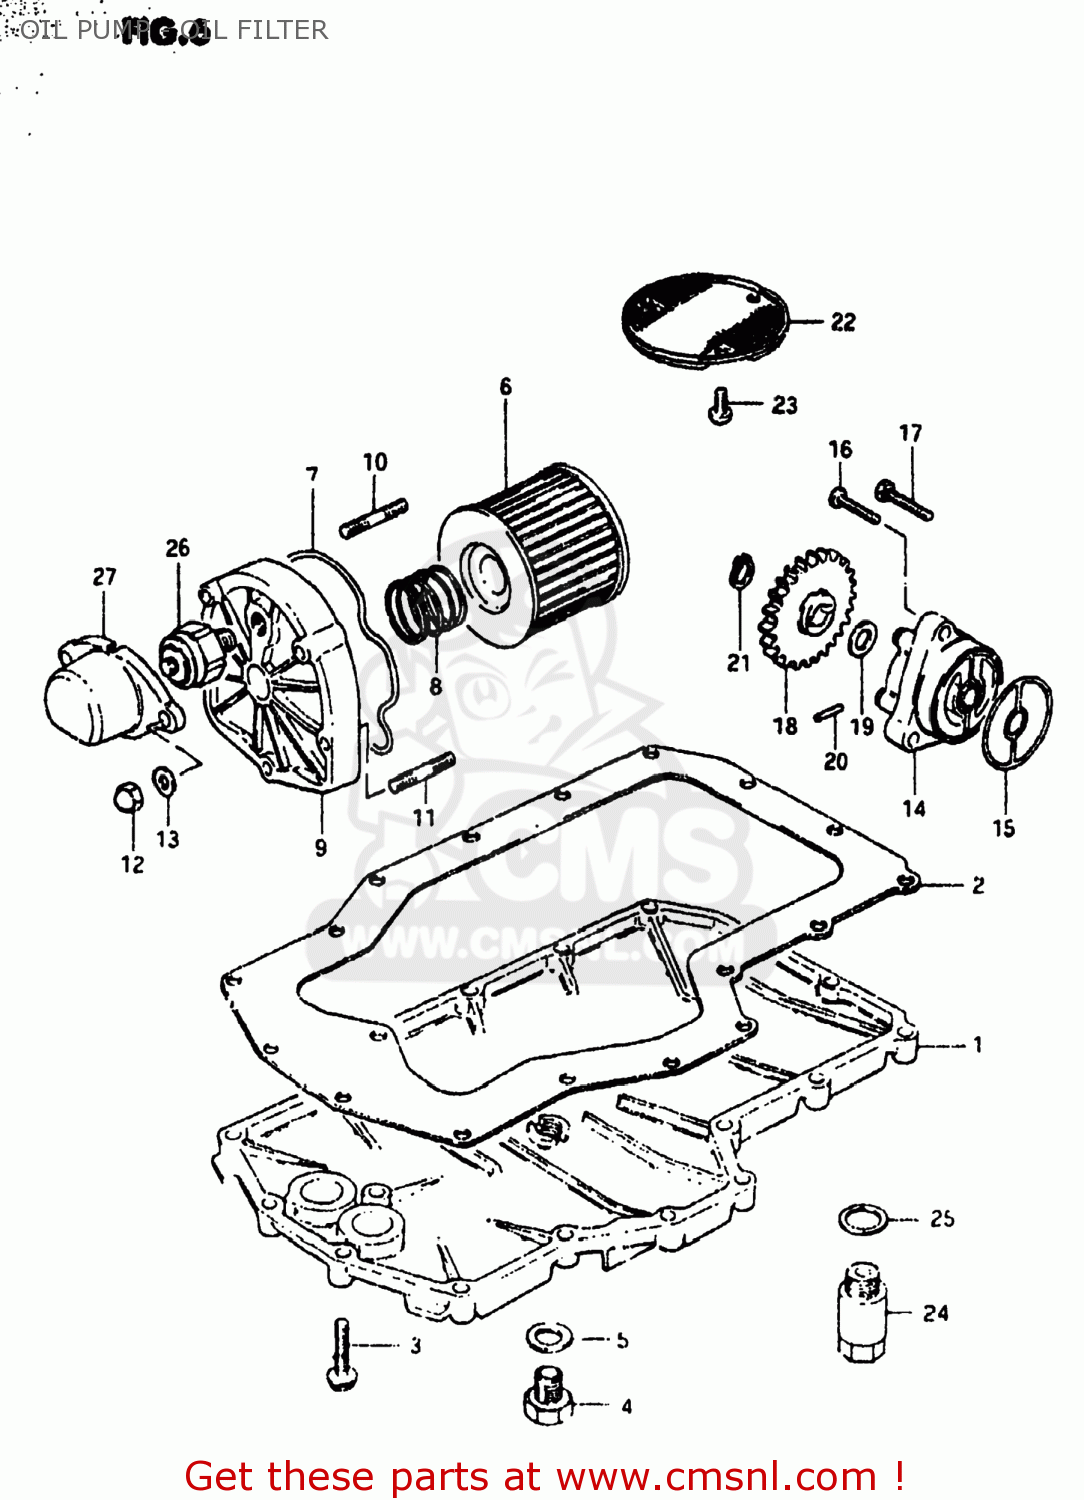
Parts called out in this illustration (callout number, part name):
1	PAN,OIL
2	GASKET,OIL PAN (MCA)
3	BOLT
4	PLUG
5	GASKET(14X19.2X2) (NAS)
6	FILTER ASSY,ENGINE OIL
7	O RING,OIL FILTER CHAMBER CAP
8	SPRING
9	CAP,ENGINE OIL FILTER
10	STUD 6X30
11	STUD 6X25
12	NUT
13	WASHER
14	PUMP ASSEMBLY,OIL
15	O-RING,OIL PUMP
16	SCREW
17	BOLT(6X32)
18	GEAR,ENG OIL PUMP DRIVEN
19	SHIM
20	PIN(4X15.8)
21	CIRCLIP
22	STRAINER,ENGINE OIL
23	SCREW 6X12
24	VALVE ASSEMBLY,OIL RELIEF
25	WASHER
26	SWITCH ASSEMBLY
27	COVER,OIL PRESSURE SWITCH
